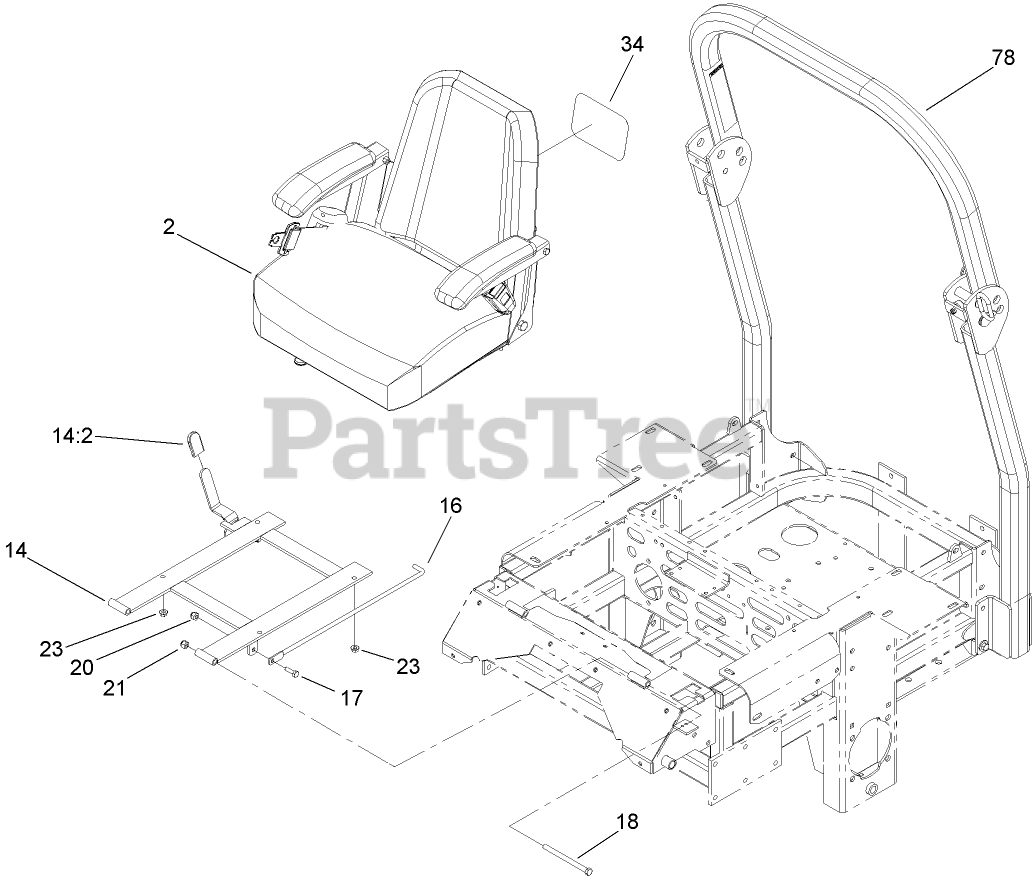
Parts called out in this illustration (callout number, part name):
2	DELUXE SEAT ASM
14	SEAT FRAME AND LATCH ASM
14:2	GRIP-LEVER
16	ROD-HOLDUP, SEAT
17	SCREW-HH
18	SCREW-HH
20	NUT-LOCK, NI
21	NUT-LOCK, NI
23	NUT-HF
34	DECAL
78	ROPS ASM
